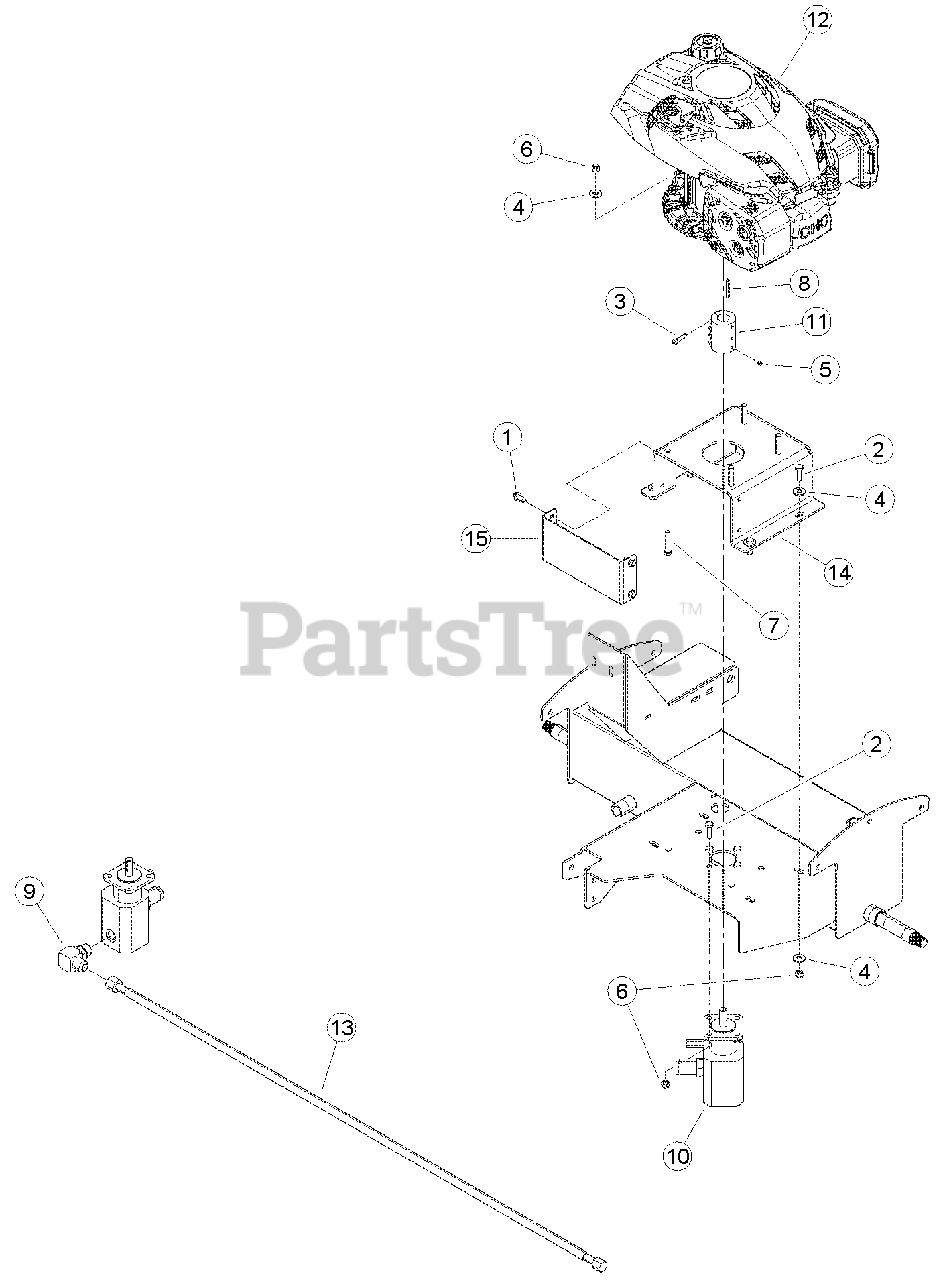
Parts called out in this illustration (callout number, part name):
1	SCREW, 11/32 X 7/8 HWH AB THREAD ZP
2	BOLT, 5/16 X 1 HEX HD GR5 NC ZP
3	BOLT, 1/4 X 1 SOC HD CAP SCRW
4	WASHER, 5/16 FLAT ZP
5	SCREW, 1/4-20 X 1/4 KNR CUP SKT SET
6	NUT, 5/16 NE NYLOCK ZP
7	BOLT, 5/16-18 X 1-3/4 HEX HD GR5 ZP
8	KEY, 3/16 SQUARE X 1-1/2 LONG
9	ADAPTER, -10 MORING / -10 MJIC 90 DEG.
10	PUMP, LOG SPLITTER 2 STAGE
11	COUPLER, SPLIT 7/8" TO 1/2" SHAFT
12	ENGINE, SUBARU EA190V (FOR SERVICE CONSULT ENGINE OWNER'S MANUAL OR YOUR NEAREST AUTHORIZED SUBARU INDUSTRIAL ENGINE DEALER)
13	HOSE, .50 X 50 -10 FJICSW / -10 FJICSW
14	MOUNT, VERT ENGINE
15	COVER, ENGINE SHAFT
